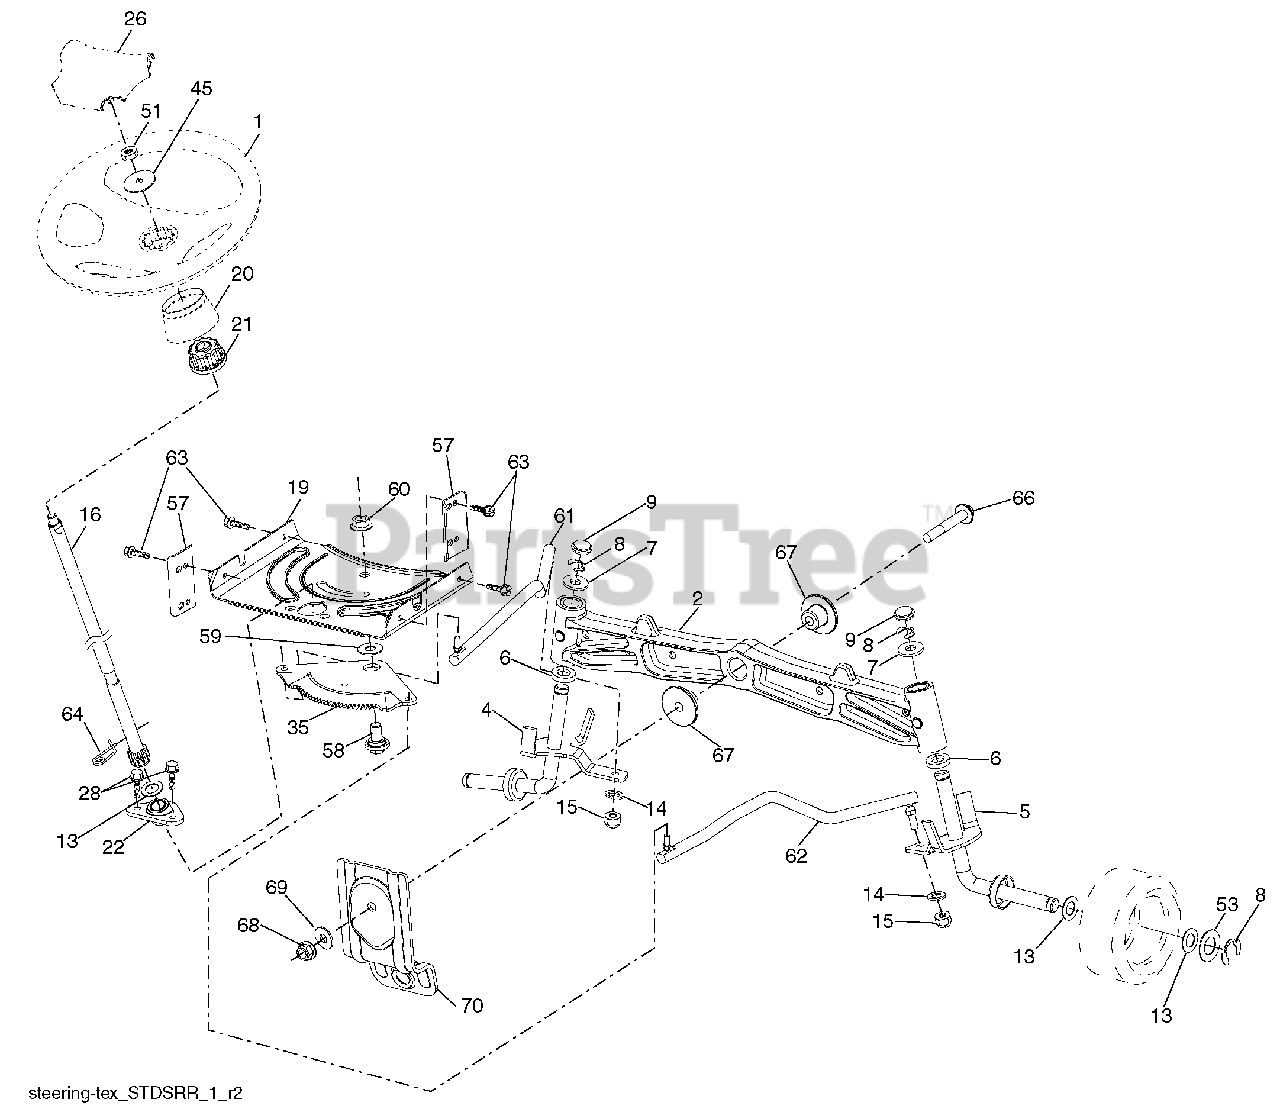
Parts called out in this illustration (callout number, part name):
1	Wheel, Steering
2	Axle Asm., Front
4	Spindle Asm., LH
5	Spindle Asm., RH
6	Bearing, Race Thrust Harden
7	Washer 25/32 x 1-5/8 x 16 Ga.
8	Ring, Clip #T5304-75
9	Cap, Spindle
13	Washer 25/32 x 1-1/4 x 16 Ga.
14	Washer, Lock Hvy Hlcl Spr 3/8
15	Nut, Crown Lock 3/8-24 unf
16	Shaft Steering
19	Plate Steering
20	Boot, Steering
21	Adapter, Wheel Steering
22	Steering Support Lower
26	Insert, Wheel Steering
28	Screw 3/8-16 x 3/4
35	Gear, Sector Plate
45	Washer 9/16 ID x 2-3/8 x 12 Ga.
51	Nut Hex Jam Toplock 1/2-20 unf
53	Washer Hardened .793 x 1.637 x .060
57	Bracket Upstop
58	Bolt Shoulder Sector Pivot CFM
59	Washer Thrust Sector Steering
60	Nut Flange Lock 5/8-11
61	Draglink, LH
62	Draglink, RH
63	Screw 5/16-18 x 3/4
64	Retainer Clip Spring Steering
66	Bolt Hex Fghd 7/16-14 x 3 Serr
67	Bushing PM Front Axle
68	Nut Lock Flange 7/16-14 Gr. 5
69	Washer 1.5 x .505 x .118
70	Bracket Deck Susp. Front
